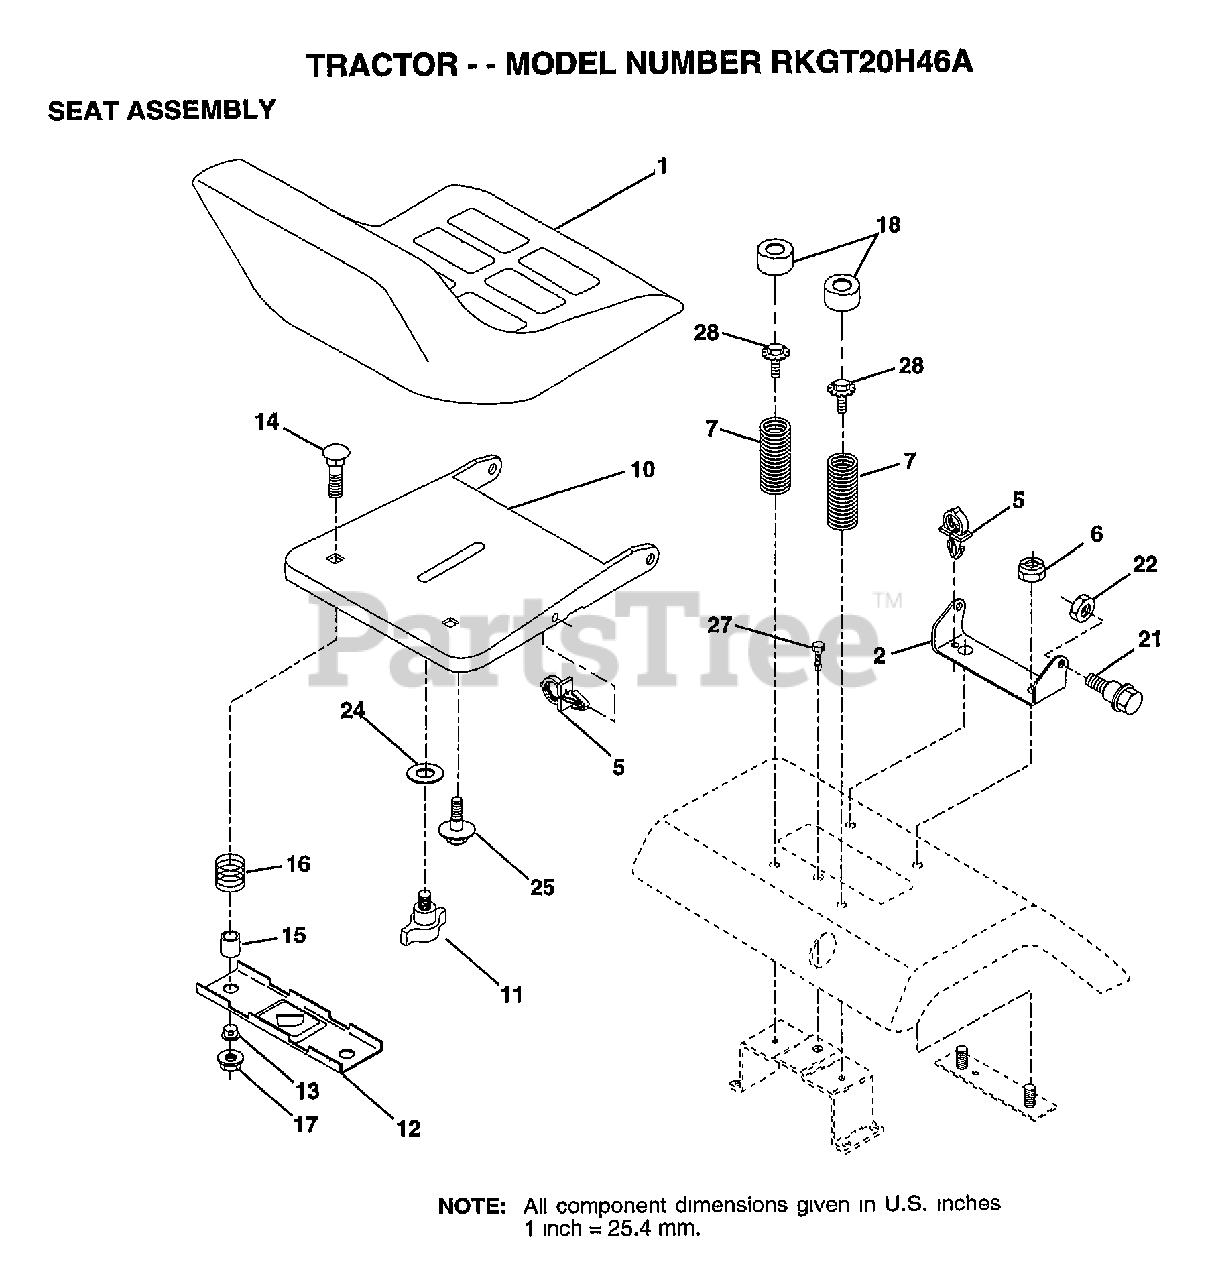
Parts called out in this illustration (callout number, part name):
1	SEAT.2500/1516.BK
2	BRACKET PVT SEAT
5	CLIP.PUSH-IN.HING
7	SPRING COMPRESSIO
10	PAN-SEAT
11	KNOB.SEAT.ADJ.WINGNUT
12	BRKT SWITCH
13	BUSHING
14	BOLT-RD HD SQ NK
15	SPACER SPLIT
16	SPRING COMPRESSED
18	CAP SPRING
21	"BOLT,SHOULDER"
22	NUT
24	WASHER
25	"BOLT,SHOULDER"
27	SCREW LT
28	BOLT.5/16-18.UNC
